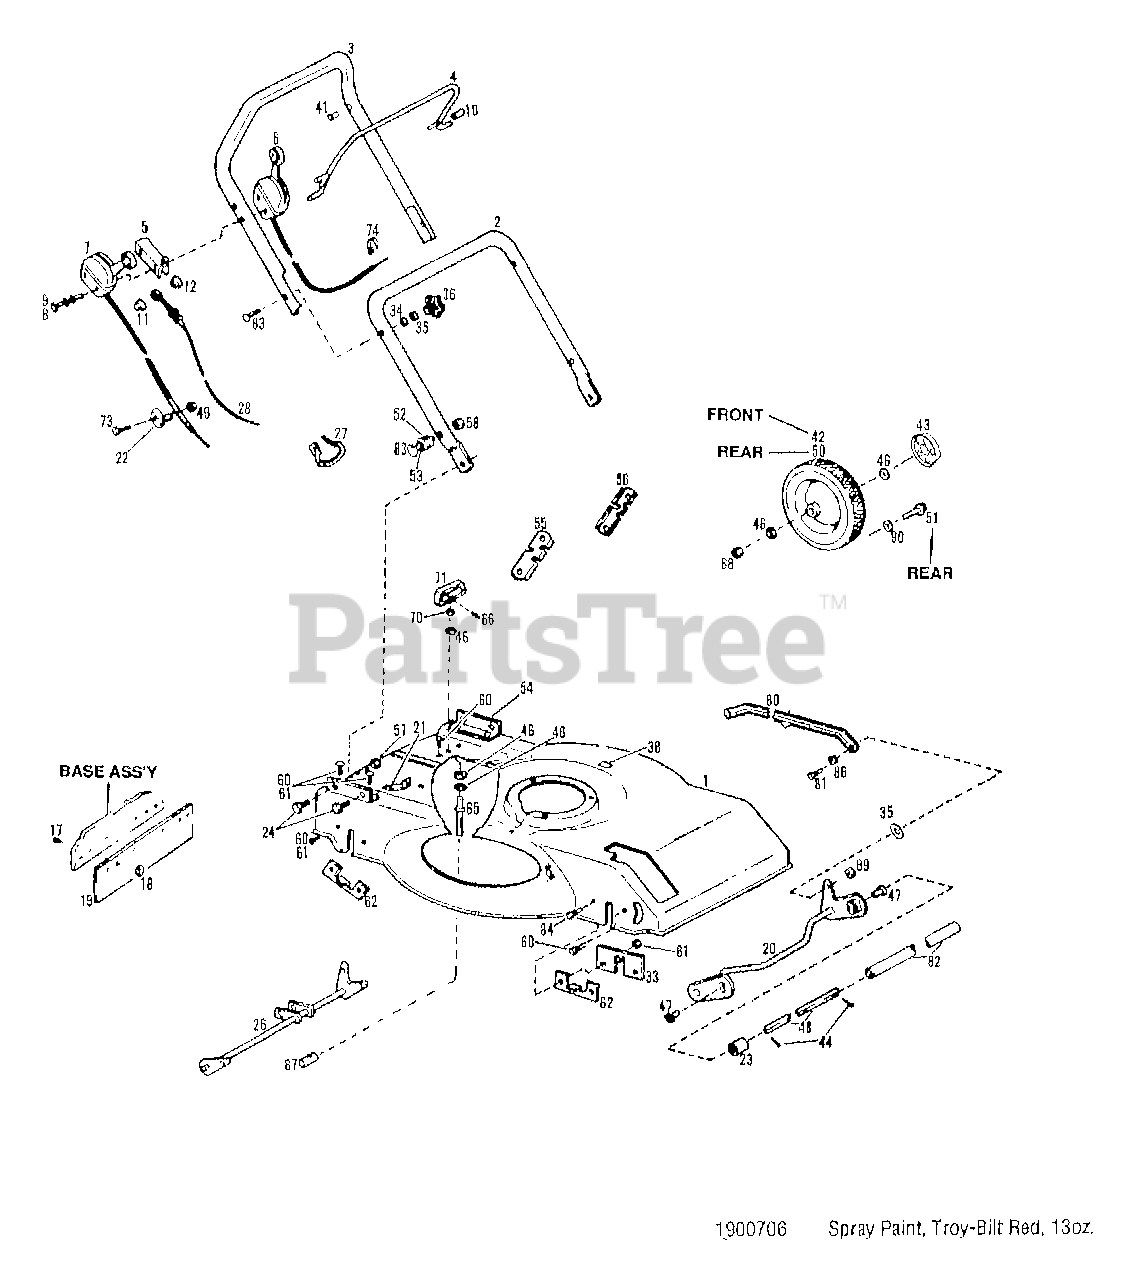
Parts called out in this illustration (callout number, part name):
1	ASSM-BASE W/DECAL 22"MLCH (INCL. 17-19 & 37 PG. 5, 64)
2	HANDLE-LOWER
3	HANDLE-UPPER
4	ASSM-BAIL ENGINE CONTROL
5	SUPPORT-CONTROL
6	THROTTLE CONTROL
6	CONTROL-THROTTLE
7	CLUTCH-CONTROL
8	SCR-HH SEMS
9	NUT W/LKWASHER 10-24 ZP
10	GRIP-HANDLE
11	CAP-PUSH ON .312 DIA
12	RING-GRIP EXT .312 ID
17	RIVET-POP (BASE ASSEMBLY)
18	WASHER-.88X.2X.059
19	SHIELD-DEFLECTOR
20	KIT-AXLE ASM FRNT (1763088)
20	ASSM-FRONT AXLE
22	CLAMP-POWDEN WIRE
23	BUSHING-AXLE
24	SCR-HH 3/8-16X.75 G5 ZP
26	ASSM-AXLE REAR
27	TIE-CABLE
28	CABLE-ENGINE BRAKE
33	PLATE-DOUBLER
34	WASHER-LK .312 ZP
35	WASHER-FLAT 5/16 SAE
38	DECAL-INDICATOR
41	BEARING-FLANGED
42	TIRE/WHEEL FRONT F/TB MULCH MW
43	CAP-HUB T/B MULCHERS
44	PIN-COTTER .125 X .75 ZP
46	WASHER-FLAT .88X.5X.06 ZP
47	BEARING-AXLE
48	AXLE-DRIVE
49	NUT-HFLK #10-24
50	ASSM-TIRE & WHEEL (REAR)
51	SCR-SHLDR 3/8-16
52	SPRING-COMPRESSION
53	SPACER
54	BRKT-HANDLEBAR
55	SUPPORT-HANDLE RH
56	SUPPORT-HANDLE LH
57	NUT-LOCK 3/8-16
58	NUT-HFT/LK
60	SCR-CARR 5/16-18X.62 G2 ZP
61	NUT-HFLK 5/16-18 ZP
62	BRACKET-AXLE
66	PIN-ROLL .188X1.0
70	SPACER-HANDLE
71	HANDLE-HEIGHT ADJ
73	SCR-HW M10-24X.88 EXTTOOTH
74	TIE-CABLE NYLON BLACK
80	LINK-HEIGHT ADJUST
81	SCR-SHOULDER
82	TUBING-PLASTIC
83	SCR-CURVED HD 5/16-18X2.0
84	SCR-TRUSS HD 5/16-18X.62
86	BEARING-NYLINER
87	PIVOT-ADJUSTING SCR
88	NUT-HFLK 3/8-16 ZP
89	NUT-HEX JAM 5/16-18
90	WASHER-1.12X.378X.125
